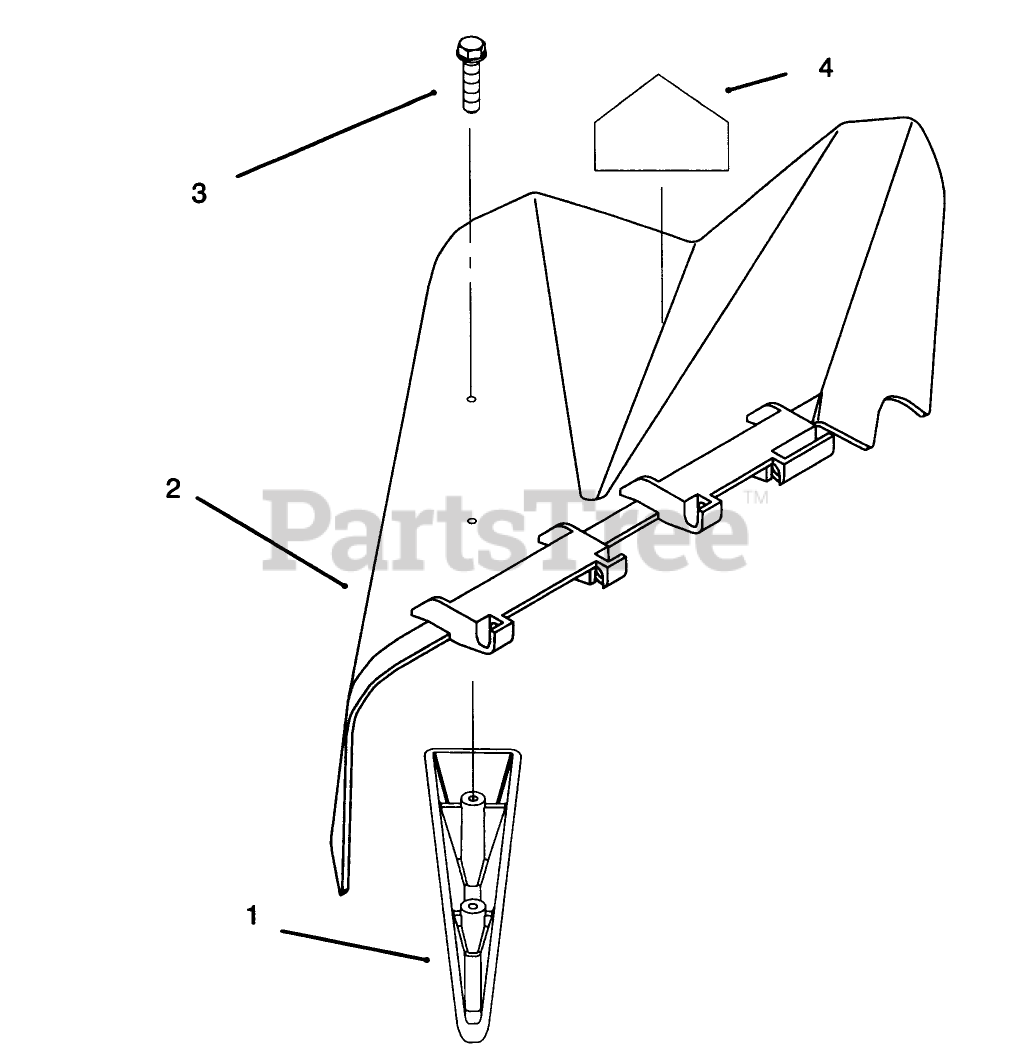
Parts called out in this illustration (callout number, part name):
1	KICKER
2	DEFLECTOR ASM
3	SCREW-PPH
4	DECAL-DANGER
